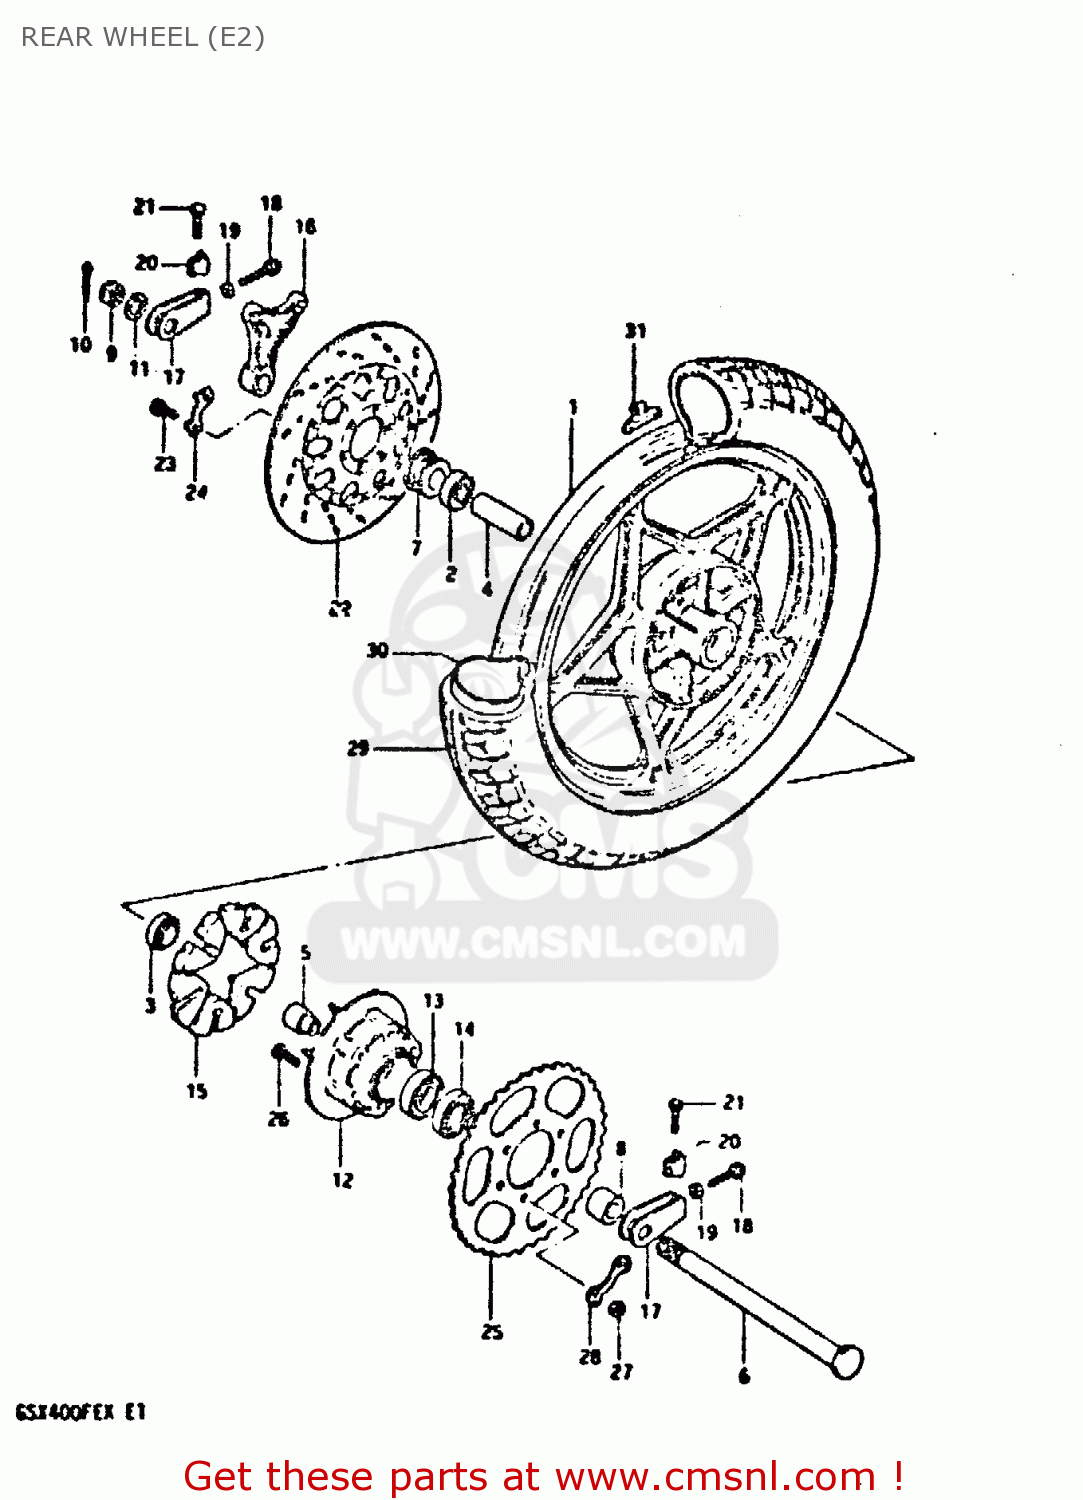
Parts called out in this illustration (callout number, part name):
1	WHEEL, REAR (18*MT*2.15)
2	BEARING
3	BEARING
4	SPACER, BEARING
5	SPACER,REAR HUB BEARING
6	AXLE, REAR
7	SPACER,REAR AXLE
8	SPACER(17X30.5X16.3)
9	NUT
10	PIN,COTTER
11	WASHER (17X30X3.2)
12	DRUM,REAR SPROCKET MOUNT
13	BEARING
14	SEAL,OIL(30.5X52X8)
15	ABSORBER,RR HUB SHOCK
16	BRACKET, REAR CALIPERS
17	ADJUSTER,CHAIN
18	BOLT
19	NUT
20	SUPPORTER,CHAIN ADJUST
21	BOLT
22	DISC, REAR BRAKE
23	BOLT(8X25)
24	WASHER
25	SPROCKET,REAR
26	BOLT
27	NUT
28	WASHER
29	TIRE (3.75S-18)
30	TUBE,INNER
31	BALANCER,WHEEL
